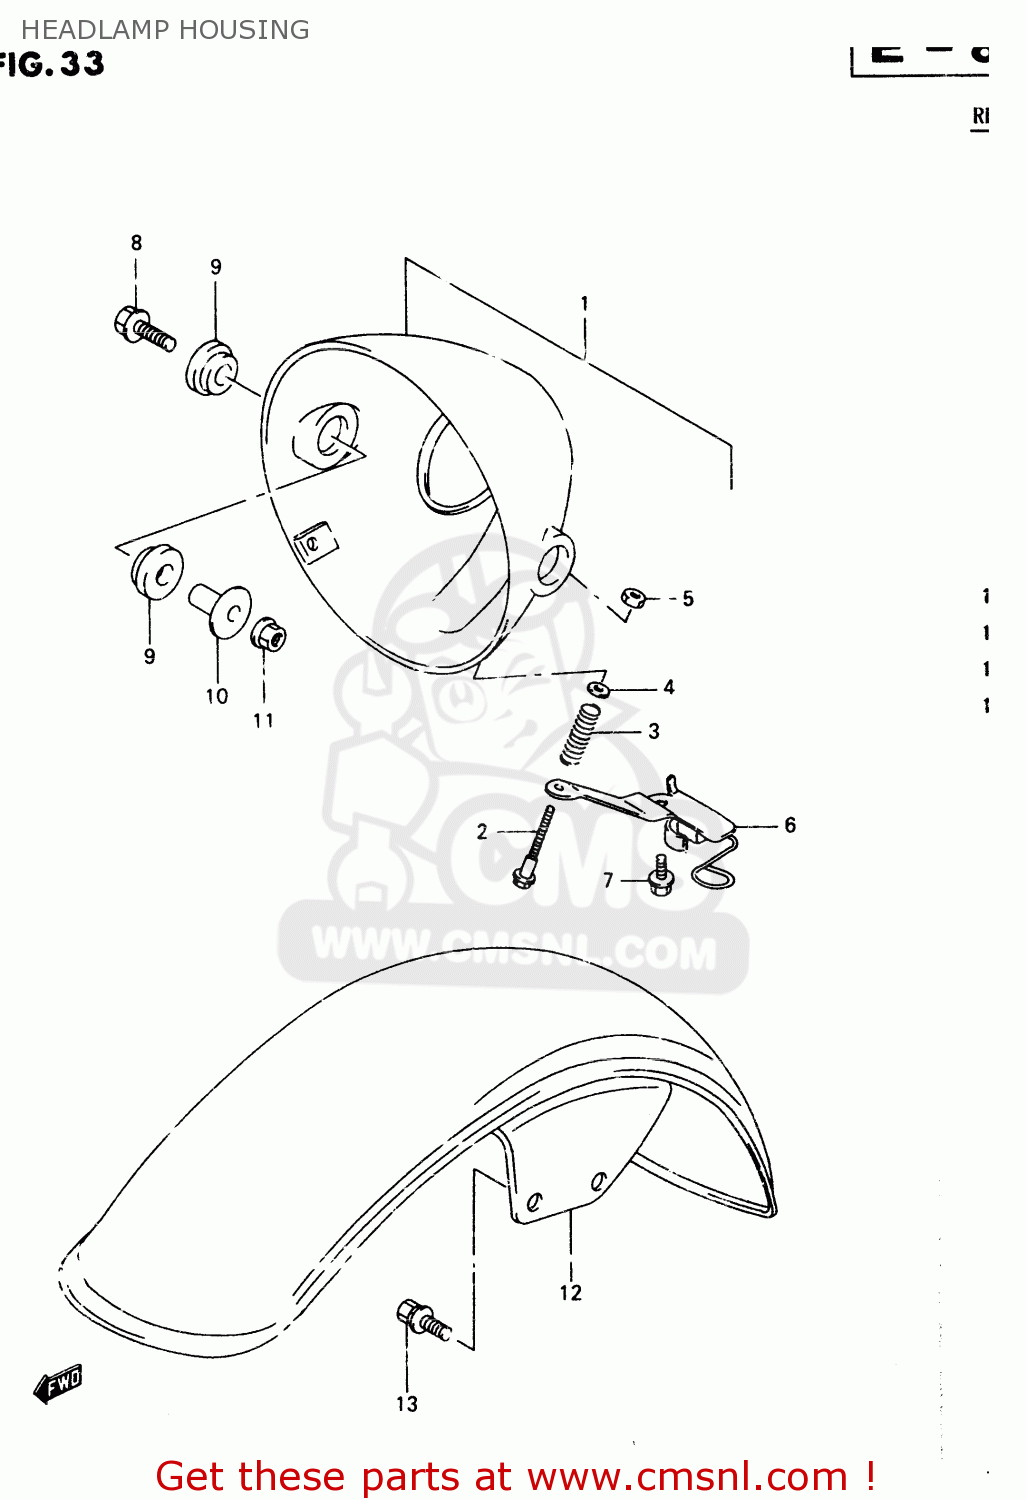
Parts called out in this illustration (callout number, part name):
1	HOUSING ASSY,HEADLAMP
2	BOLT,HEADLAMP ADJUSTER
3	SPRING,HEADLAMP ADJUSTER
4	WASHER
5	NUT,HEADLAMP ADJUSTER
6	PLATE,HEADLAMP HOUSING
7	BOLT
8	BOLT
9	CUSHION
10	SPACER(8.6X12X20)
11	NUT
12	FENDER,FR
13	BOLT, UPPER
